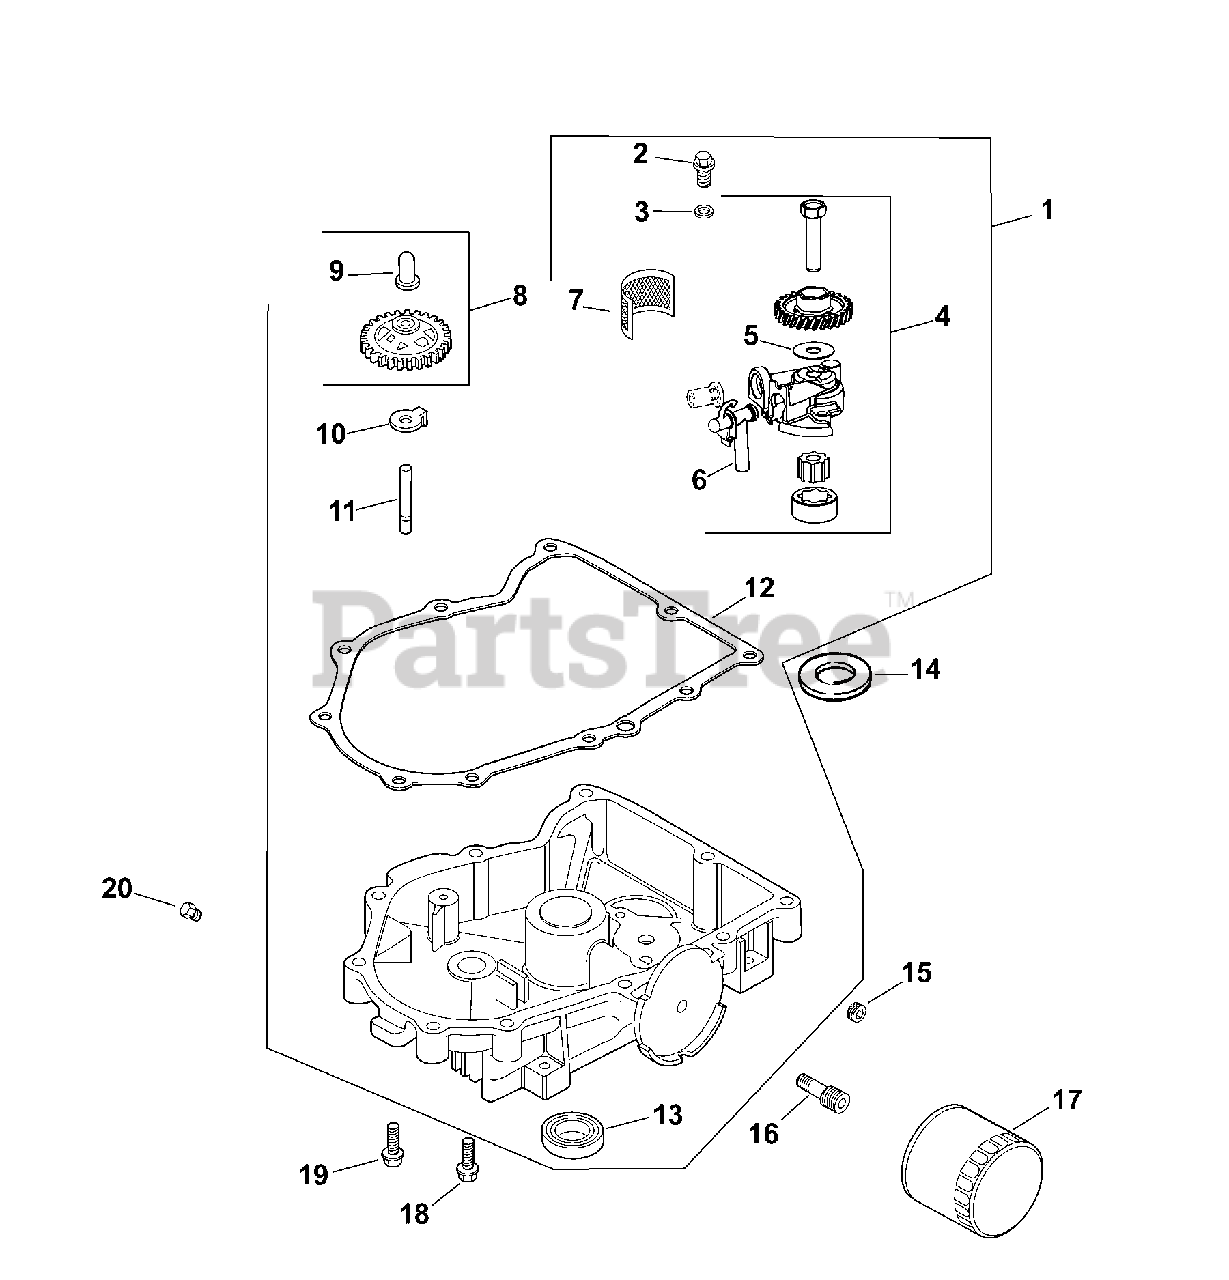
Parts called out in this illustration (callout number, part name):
1	KIT, OIL PAN ASSEMBLY - (#2419932S)
2	SCREW,FLG THD FRM M6X1.0X25-(#25086395S)
3	WASHER, FLAT 6 MM
4	OIL PUMP ASSY KIT-USE 24 393 53-S
5	O-RING, OIL PICK-UP
6	KIT, OIL PICK-UP TUBE
7	SCREEN, OIL
8	KIT, GOVERNOR GEAR W/PIN
9	PIN, GOVERNOR REGULATING
10	TAB, LOCKING
11	SHAFT, GOVERNOR GEAR
12	KIT,OIL PAN GASKET USE 24 041 66-S
13	SEAL, OIL (KM)-USE 25 032 06-S
14	SHIM, THRUST
15	PLUG, PIPE CTSK 3/8"
16	NIPPLE, OIL FILTER
17	OIL FILTER
18	SCREW, FLG M8X1.25X45
19	SCREW, HEX FLANGE -USE 24 086 17-S
20	PLUG, HD PIPE 3/8"
